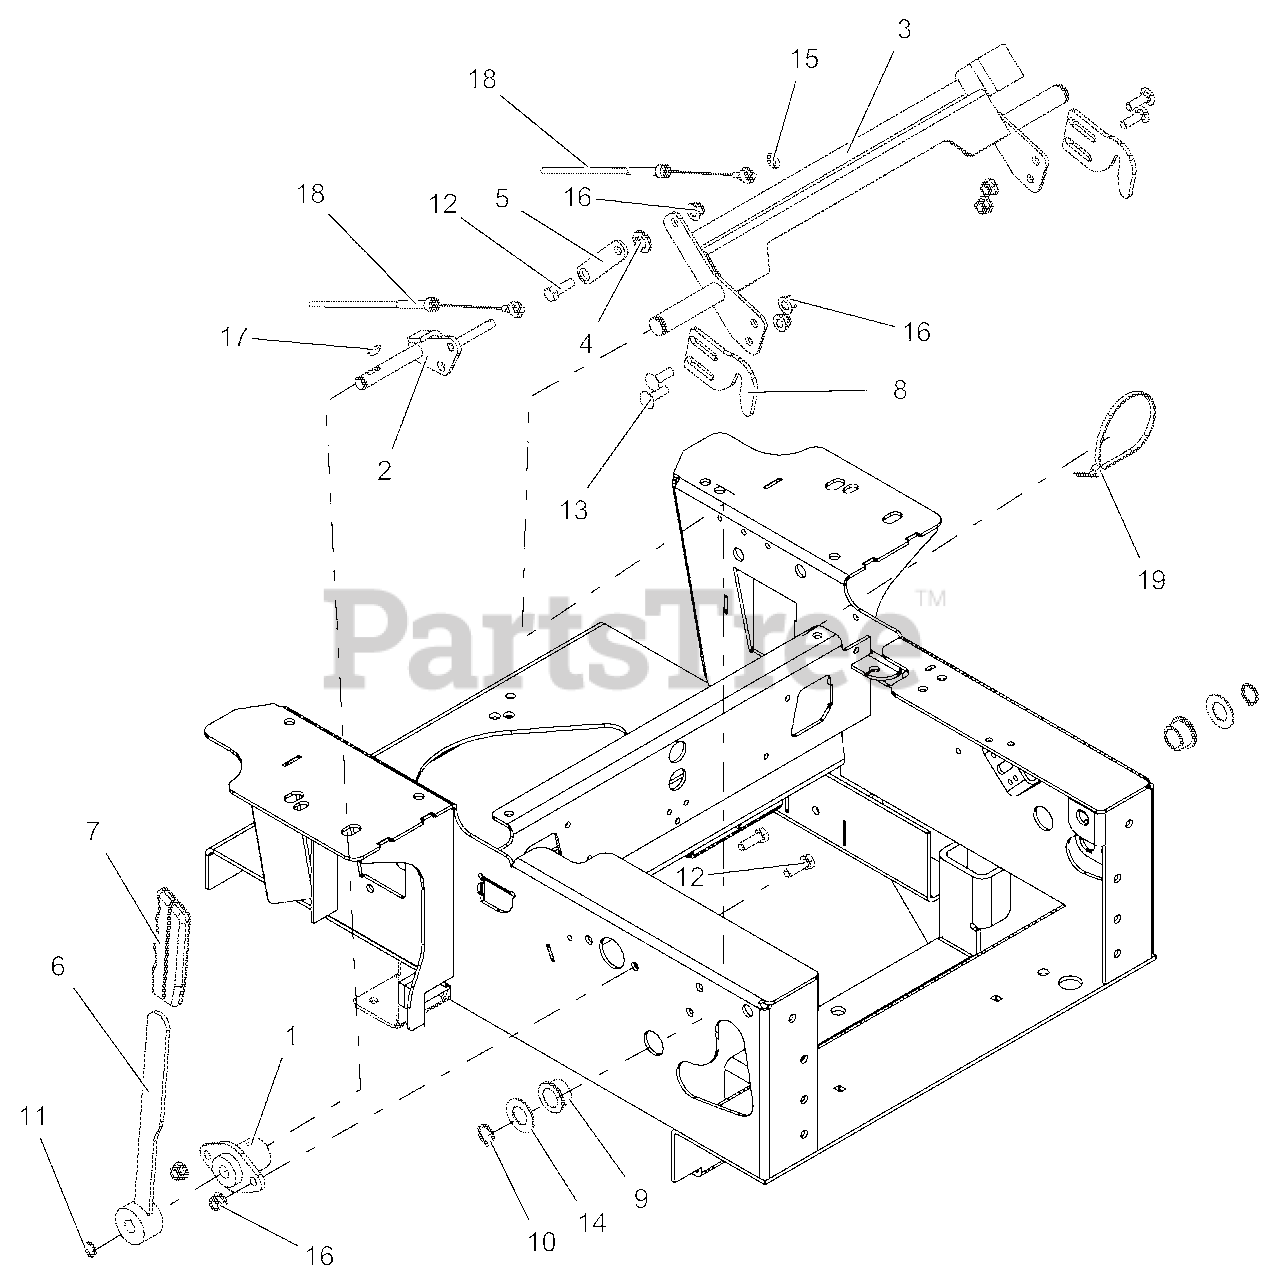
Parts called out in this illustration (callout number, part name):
1	BSHG, FLANGE .500 ID
2	WLDMT, PARK BRAKE ARM
3	WLDMT, PT100 NEUTRAL LOCK
4	BSHG, FLG .325X.499X.26X.88
5	PLATE, NEUTRAL INTERLOCK
6	WLDMT, PARKING BRAKE ARM
7	GRIP, PARKING BRAKE (YELLOW)
8	NEUTRAL, LOCK LATCH-BLACK
9	BSHG, FLG .750X1.00X.625X1.25
10	RG-RTNG-EXT .750x.078
11	RG-RTNG-EXT .500x.050
12	BLT-HEX .31-18X1.00 GR5 YWZC
13	BLT-RDHDSQSHNK .31-18X1.00 G5 Y
14	WSHR-FL-STL .755X1.375X.062 YWZC
15	NUT, PUSH .312
16	NUT-LK-NYL-FLG .31-18 YWZC
17	KEY, WDRF .13x.63 HRD#5 GM124545 P
18	CABLE, BRAKE ACTUATING
19	CABLE, TIE 5.50 LG
